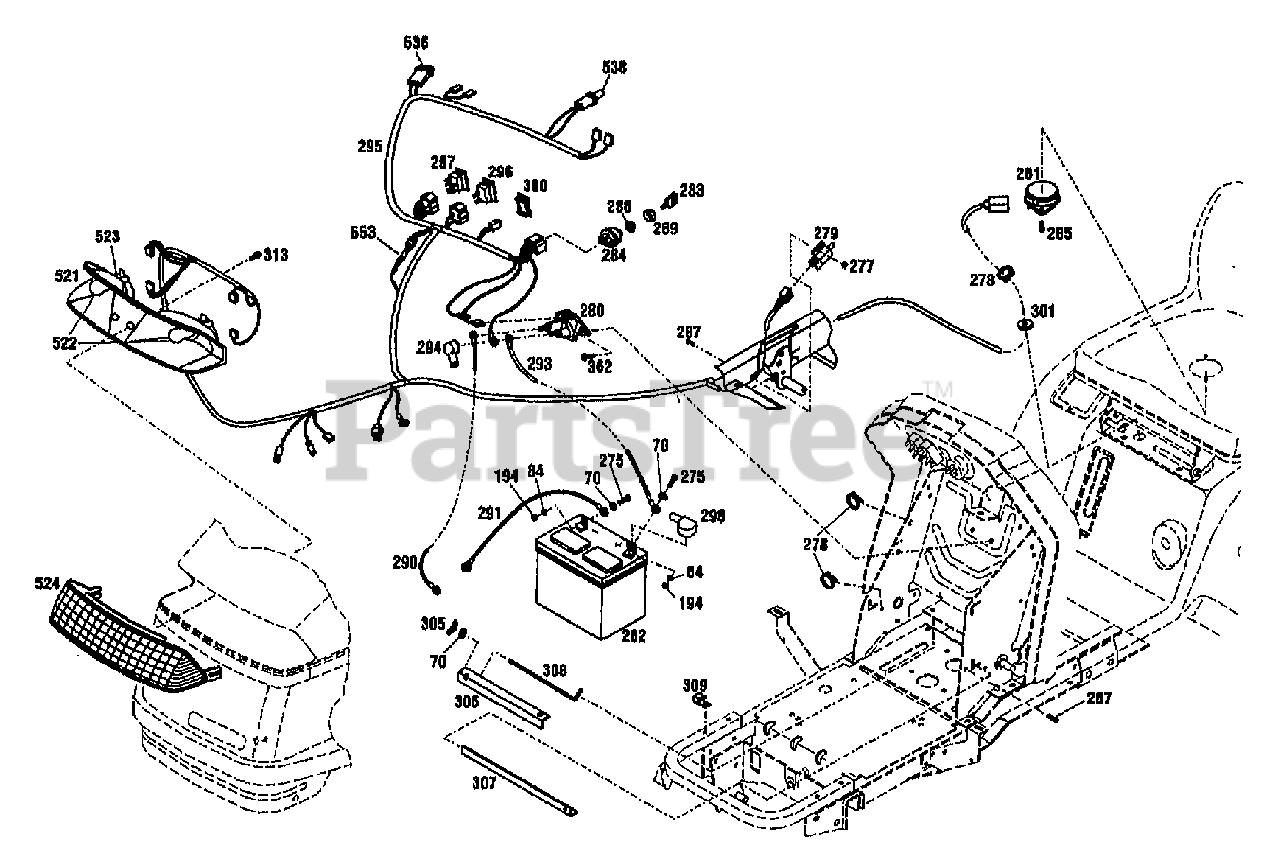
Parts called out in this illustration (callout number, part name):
70	WASHER-FLAT 1/4 SAE
84	WASHER-LK .25 ZP
194	NUT-HEX 1/4-20 ZP
275	SCR-HH 1/4-20X.625 G5 ZP
277	NUT W/LKWASHER 10-24 ZP
278	TIE-CABLE NYLON BLACK
279	SWITCH
280	SOLENOID
281	SWITCH-SEAT
282	BATTERY
283	KEY-IGNITION
284	SWITCH-IGNITION
285	SCR-PHP 1/4-20X.50 ZP
287	SCR-HHS 10-24X.625 ZP
288	NUT-SWITCH
289	CAP-SWITCH
290	CABLE-STARTER
291	CABLE-BATTERY (-)
293	CABLE-BATTERY
294	BOOT-SOLENOID
295	HARNESS-MAIN WIRING
296	SWITCH-LIGHT
297	SWITCH-PTO
298	BOOT-TERMINAL
300	COVER-SWITCH
301	GROMMET
305	NUT-WING
306	CLAMP-BATTERY
307	BRKT-BATTERY LOWER
308	SCR-HOOK
309	CLIP-J
362	SCR 1/4-20X.5 FL SELF TAP
521	ASSM-HEADLIGHT
522	LIGHTBULB
523	SOCKET
524	LENSE-HEADLIGHT
536	FUSE
538	LIGHTBULB
553	ASSM-DIODE
